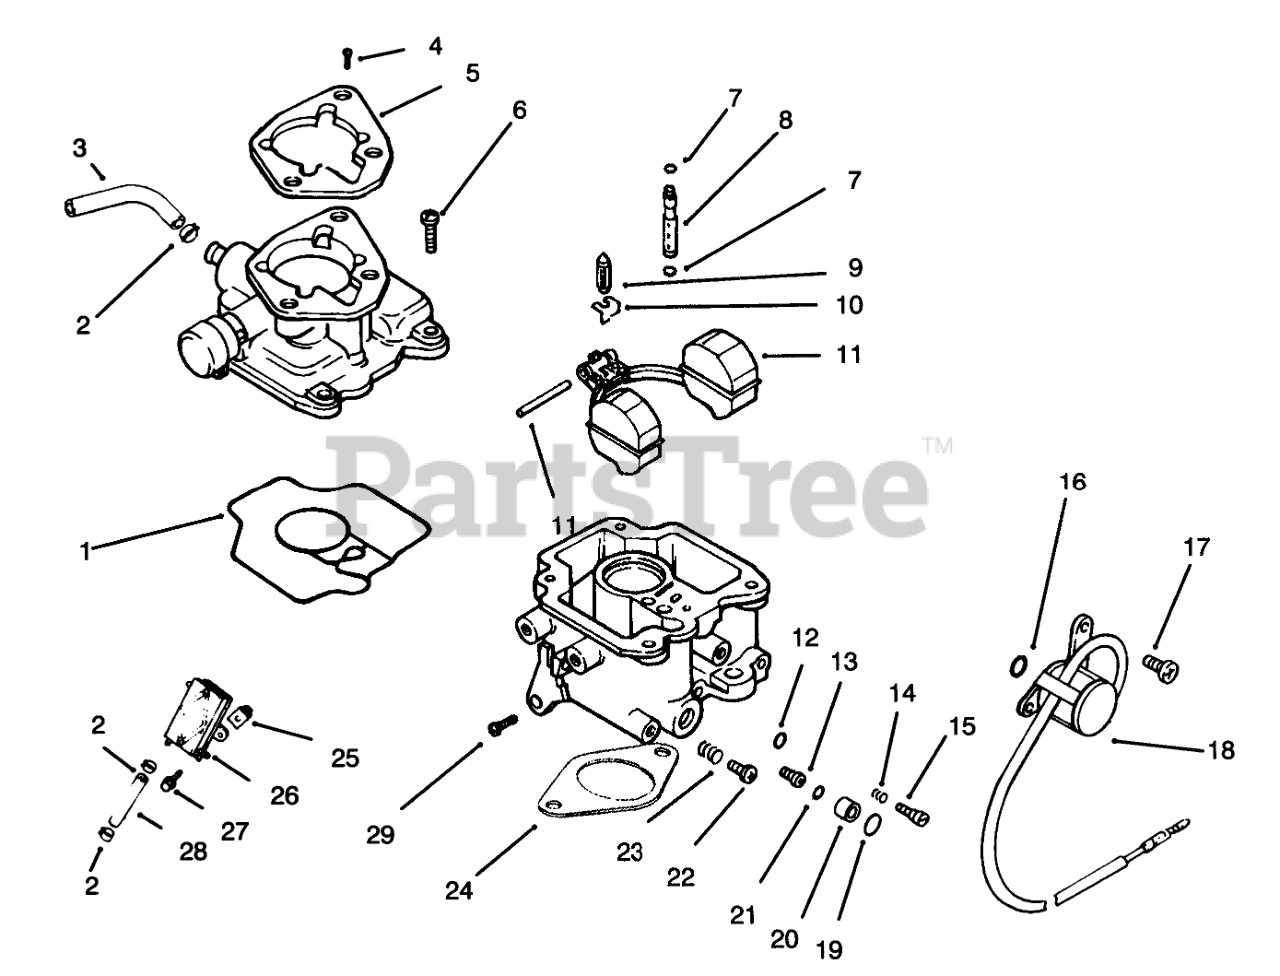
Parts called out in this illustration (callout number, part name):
1	Gasket-Carburetor Body
2	Clamp
3	Line-Fuel
5	Gasket-Air Cleaner
7	"O"Ring
8	Jet-Slow
9	Valve-Inlet Needle
10	Clip-Inlet Needle Valve
11	Kit-Float Repair
12	"O"Ring
13	Jet-Main
14	Spring-Idle Adjust
15	Needle-Idle Adjust
16	"O"Ring
18	Solenoid
19	"O"Ring
20	Seat-Solenoid
21	"O"Ring
22	Screw-Idle Speed Adjust
23	Spring-Idle Speed Adjust
24	Gasket-Carburetor
26	Pump-Fuel
28	Line-Fuel 15-1/2"
29	Screw-Throttle Stop
